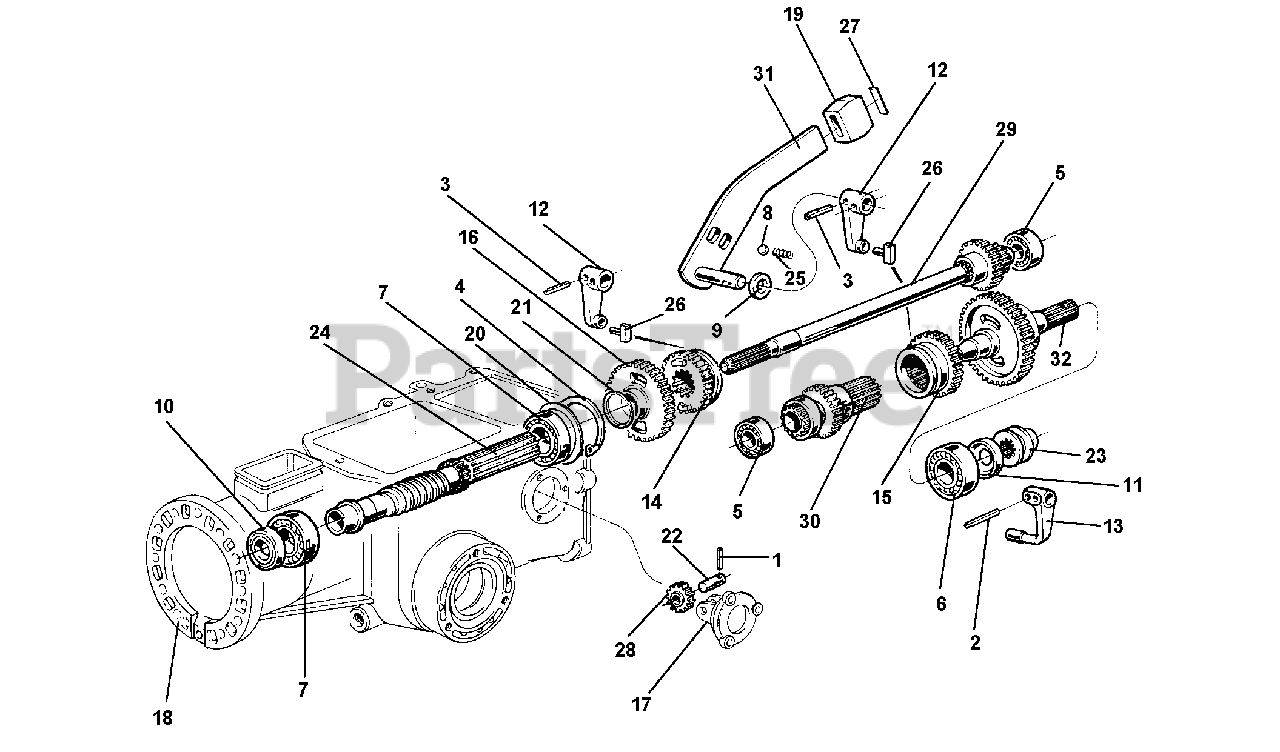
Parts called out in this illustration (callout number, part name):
1	PIN, LOCKING 2.5 X 22 DIN 1481
2	LOCKING PIN 4 X 20 SPIRAL
3	LOCKING PIN 4 X 24 SPIRAL
4	CIRCLIP, INTERN D 52
5	BEARING 15 X 35 X 11 6202
6	BEARING 20 X 47 X 14 6204
7	BEARING SKF 25 X 52 X 15 6205
8	BALL 15/32 RIV RB-11.906
9	SEAL, OIL 12 X 19 X 5 STANDARD
10	SEAL, OIL 15 X 40 X 10 STANDARD
11	SEAL, OIL 20 X 35 X 7 STANDARD
12	LEVER, SPEED CHG SLDG GR
13	SLIDE LEVER
14	SLIDER SPEEDS
15	SLIDER REDUCTION UNIT
16	WHEELS FIRST SPEED
17	FLANGE, REVERSE SPEED
18	CASING 5 SPEEDS GEARBOX
19	KNOB REDUCTION UNIT LEVER
20	RING C - 72
21	WASHER 25 X 32 X 2 C - 72
27	DECAL SLOW/FAST SPEEDS
28	REVERSE SPEED GEAR
29	CLUTCH SHAFT
30	GEAR TRIPLE
31	LEVER REDUCTION UNIT
32	P.T.O. SHAFT
